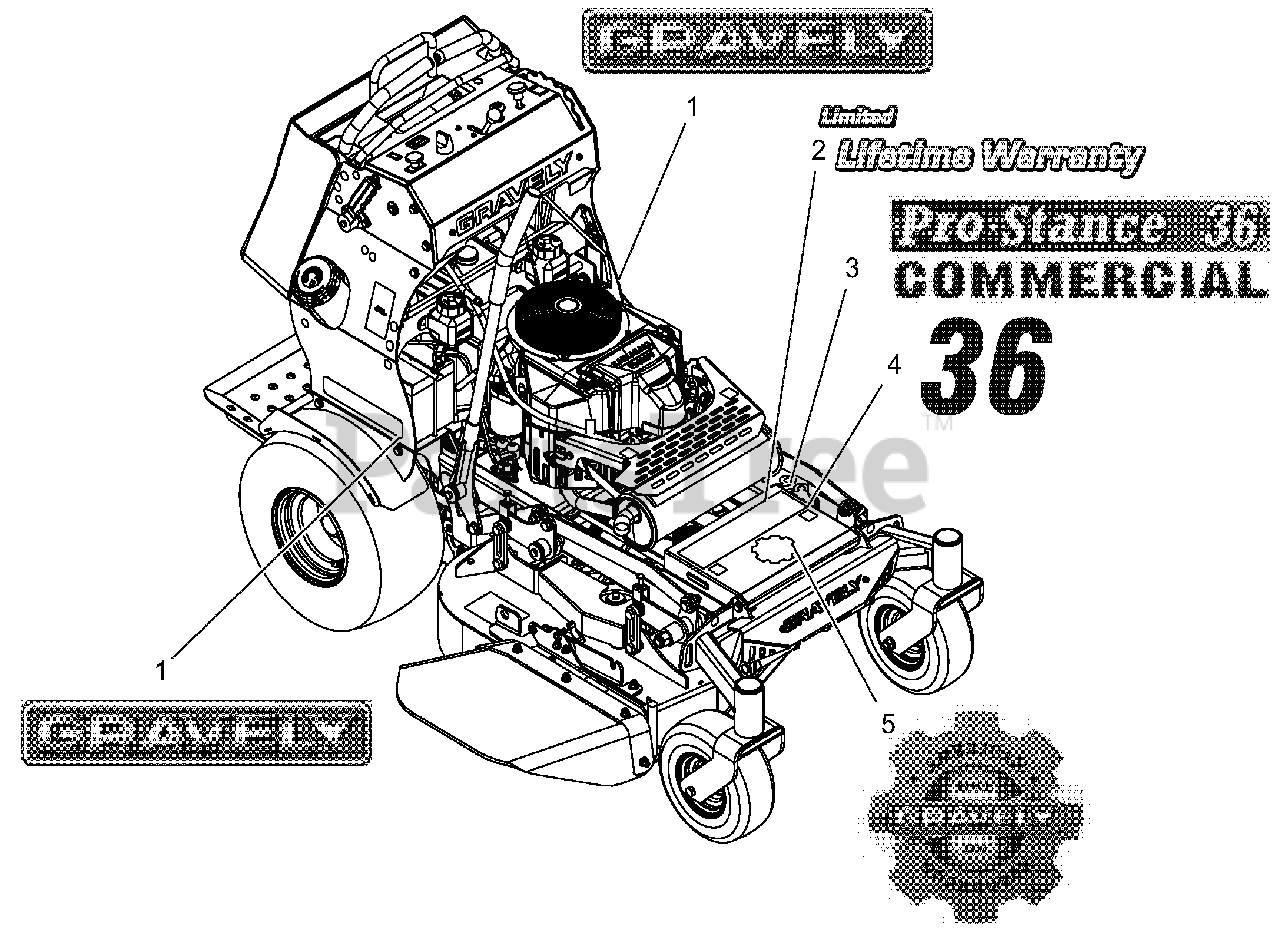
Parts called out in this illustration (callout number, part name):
1	DECAL, 9.5" GRAVELY LOGO
2	DECAL, LIMITED LIFETIME WARRANTY REV
3	DECAL, DECK SIZE, 36"
4	DECAL, PRO-STANCE 36
5	DECAL, GRAVELY HERITAGE-LARGE
